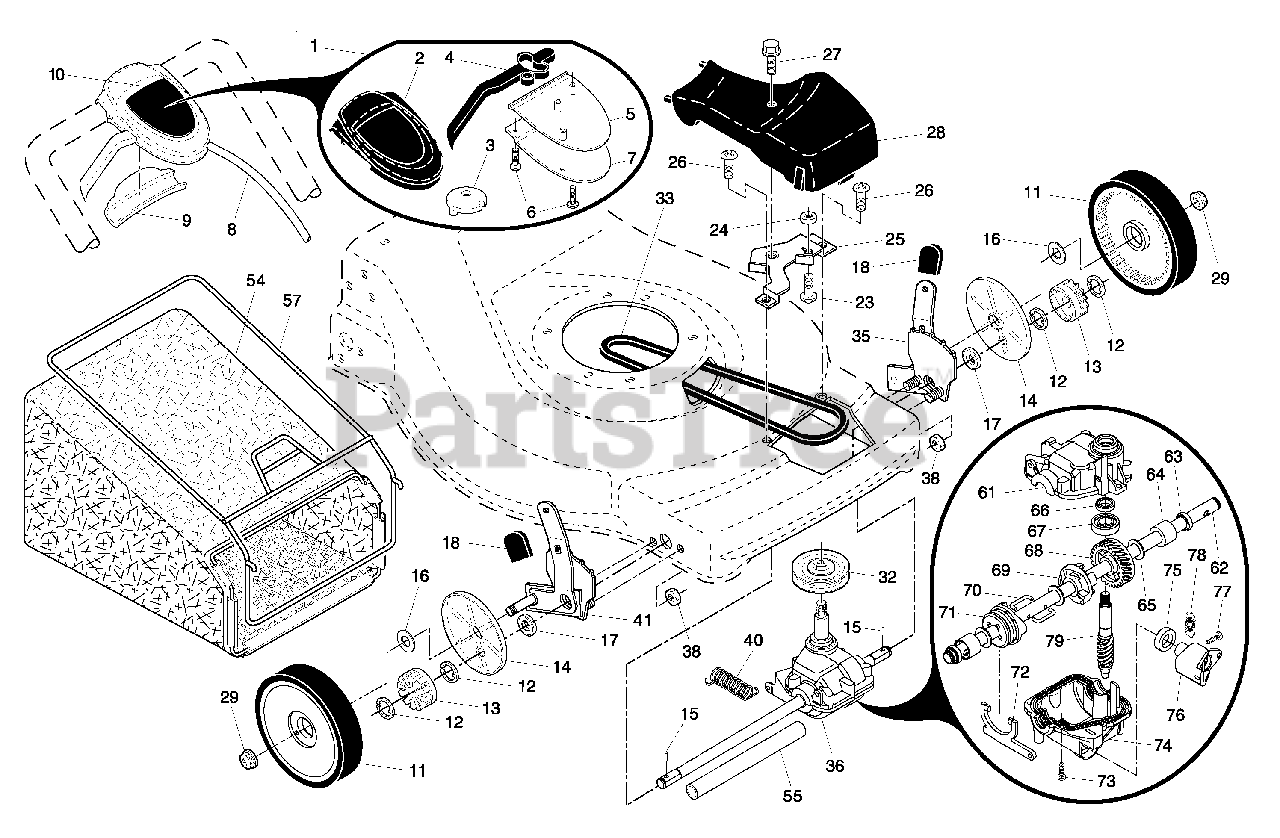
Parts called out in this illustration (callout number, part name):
1	Drive Control Assembly
2	Cover, Drive Control, Top
3	Pulley
4	Lever, Drive Control
5	Cover, Drive Control, Bottom
6	Screw, Torx Head #8 x 5/8
7	Mounting Bracket, Drive Control
8	Cable, Drive Control
9	Cap, Drive Control, Bottom
10	Decal, Drive Control
11	Wheel & Tire Assembly
12	E-Ring
13	Gear, Pinion
14	Dust Cover
15	Pawl, Drive
16	Washer, Flat 3/8
17	Bearing, Wheel Adjuster
18	Selector Knob
23	Screw 1/4-20 x 1-1/4
24	Nut, Hex
25	Belt Guide Bracket
26	Screw
27	Pan Head Tapping Screw #10-24 x 2-3/4
28	Drive Cover
29	Locknut, Hex
32	Drive Pulley
33	V-Belt
35	Kit, Wheel Adjuster, LH
36	Gearcase Assembly, Complete
38	Locknut, Hex 1/4-20
41	Kit, Wheel Adjuster, RH
54	Grassbag Assembly
55	Driveshaft Cover
57	Frame, Grassbag
61	Case, Upper
62	Shaft, Output
63	Seal, Output Shaft
64	Bushing
65	Washer
66	Seal, Worm Shaft
67	Bearing, Ball
68	Gear, 27 Teeth
69	Fixed Dog Clutch
70	Wireform
71	Movable Dog Clutch
72	Fork
73	Screw, Case
74	Case, Lower
75	Seal, Lever
76	Lever
77	Screw, Lever
78	Spring
79	Shaft, Worm
